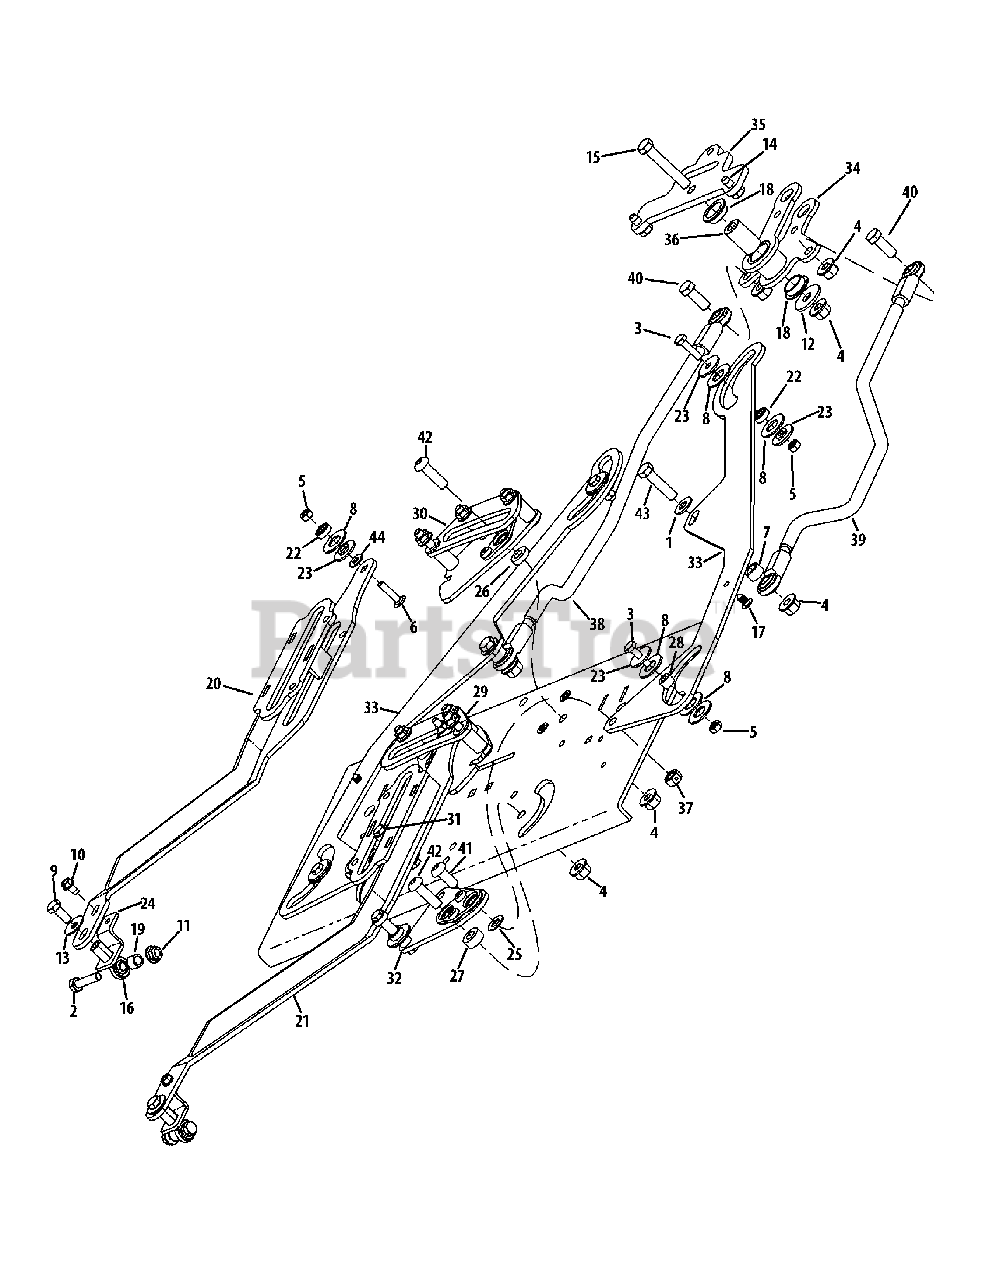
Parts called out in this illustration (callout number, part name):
1	Washer, .406 x .813 x .063
2	Hex Screw, 5/16-18 x 1.25
3	Hex Screw, 1/4-20 x 1.00
4	Flange Counter Lock Nut, 3/8-16
5	Counter Lock Nut, 1/4-20
6	Carriage Bolt, 1/4-20 x 1.00
7	Spacer, .407 x .625 x .375
8	Washer, .550 x 1.25 x .068
9	Hex Screw, 5/16-24 x .750
10	Hex Flange Screw, 1/4-20 x .500
11	Flange Counter Lock Nut, 5/16-18
12	Washer, .411 x 1.25 x 1.00
13	Bell Washer, .325 x .930 x .045
14	Flange Screw, 5/16-18 x .75
15	Hex Screw, 3/8-16 x 2.25
16	Rod End, 5/16
17	Nylon Rivet, 1/4 x .625
18	Flange Bearing, .752 x 1.25 x .305
19	Spacer, .344 x .500 x .375
20	RH Pump Control Bracket Assy.
21	LH Pump Control Bracket Assy.
22	Ball Bearing, .25 x .625 x .196
23	Shoulder Spacer, .251 x 1.00 x .06
24	Rod Support End Bracket
25	Spacer, .381 x .750 x .040
26	Spacer, .381 x .75 x .150
27	Spacer, .381 x .750 x .312
28	Spacer, .256 x .500 x .330
29	LH Speed Control Cam Assembly
30	RH Speed Control Cam Assembly
31	LH Steering Pivot Assembly
32	RH Steering Pivot Assembly
33	Control Link Plate
34	Front Steering Pivot Assembly
35	Steering Pivot Mount Plate
36	Spacer, .385 x .750 x 1.28
37	Counter Lock Nut, 3/8-16
38	LH Control Rod Assembly
39	RH Control Rod Assembly
40	Hex Screw, 3/8-16 x 1.00
41	Screw, 3/8-16 x .875
42	Screw, 3/8-16 x .1.25
43	Hex Screw, 3/8-16 x 1.50
44	Flat Washer, .25 x .630 x .0515
